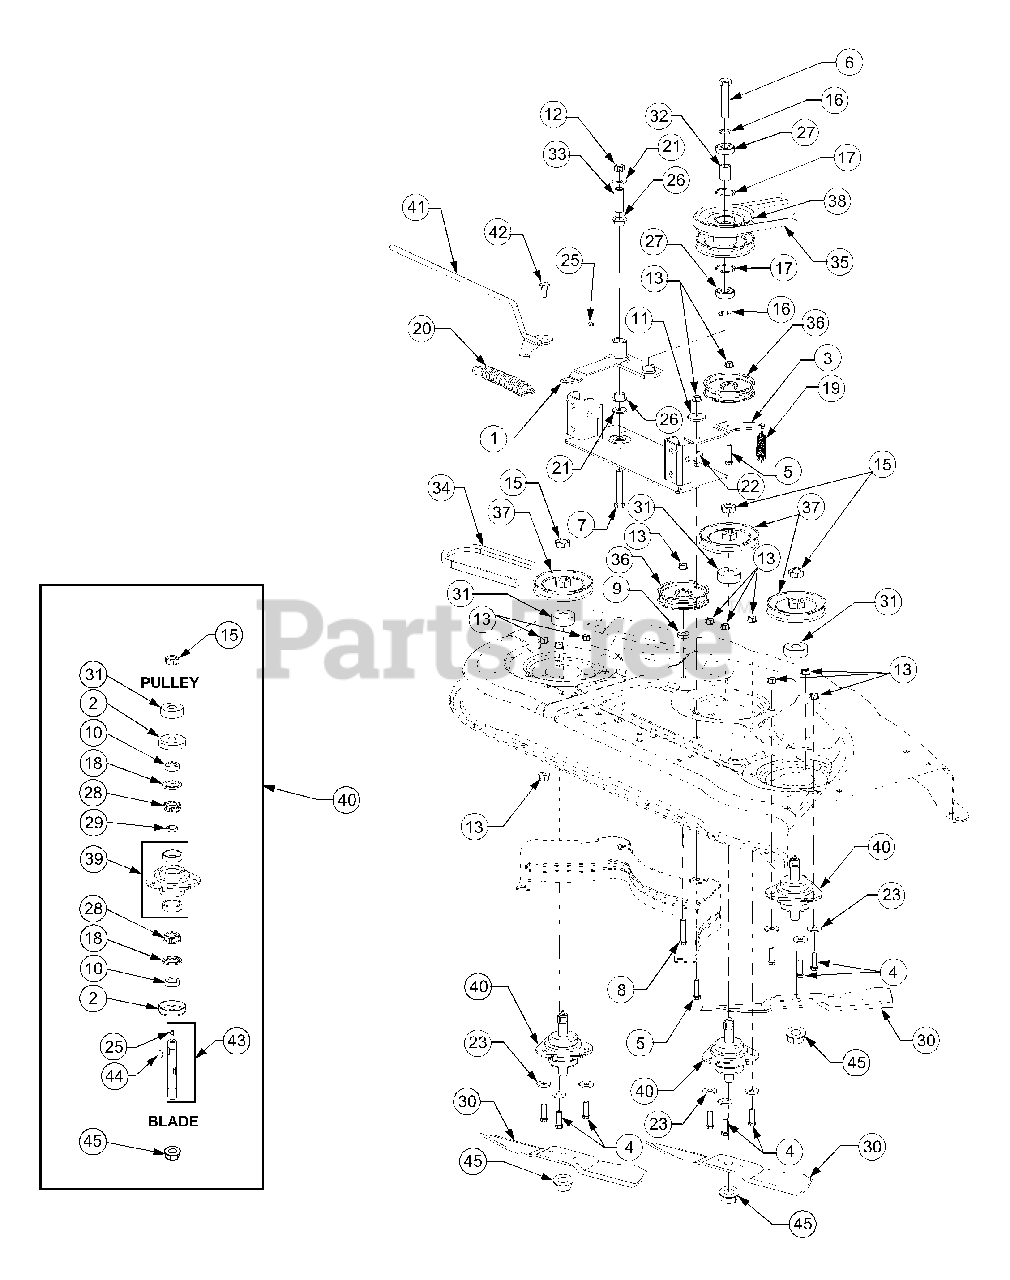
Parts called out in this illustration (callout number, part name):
1	Pivot Arm, Double Pulley
2	Cup, Spindle
4	Screw, Hex Cap 3/8-16 x 1.25 GR5
5	Screw, Hex Cap, 3/8-16 x 1.5 GR5
6	Screw, Hex Cap, 5/8-18 x 3 GR5
7	Screw, Hex Cap, 1/2-20 x 3 GR8
8	Screw, Hex Cap, 3/8-16 x 2
9	Spacer, .380 ID x 1 OD x .32
10	Spacer, .755 ID x 1.25 OD x .44
11	Spacer, Shoulder
12	Nut, Hex Center Lock, 1/2-20
13	Nut, Hex Flanged Lock, 3/8-16
15	Nut, Hex Jam, 3/4-16 GR5
16	Washer, Flat, .65 x 1.25 x .075
17	Snap Ring, Internal
18	Seal, Oil, 1.25 x 1.874 x .25
19	Spring, Extension, .75 OD x 6.12
20	Spring, Extension, 1.25 OD x 8.15
21	Washer, Flat, .531 x 1.25 x .1 Thk
22	Washer, Flat, .385 x 1 x .127 Thk
23	Washer, Flat, .406 x 1.0 x .105
25	Fitting, 3/16 Drive Lube
26	Bearing, Flange, 3/4 ID x .53
27	Bearing, Ball, .62 x 1.57 x .470
28	Cone, Bearing
29	Spacer, Bearing
30	Blade, Low Lift, 16.5"
31	Spacer
32	Spacer, Pulley, .635 ID x .88 OD x
33	Spacer, Idlr Brkt, .51 ID x .75 OD x
34	Belt, Spindle, A-Section x 105"
35	Belt, PTO, B-Section x 111.2"
36	Pulley, Flat Idler, 4.06 OD
37	V-Pulley, 4.70 OD
38	Pulley, Double
39	Housing w/Cups, Spindle
40	Spindle Ass'y, Blade
42	Bolt, Shoulder, .498 Dia. x .340
43	Kit, Shaft w/Seal
44	Key, #91 Woodruff, 1/4 x 3/4
45	Nut, Hex Flange, 3/4-16
